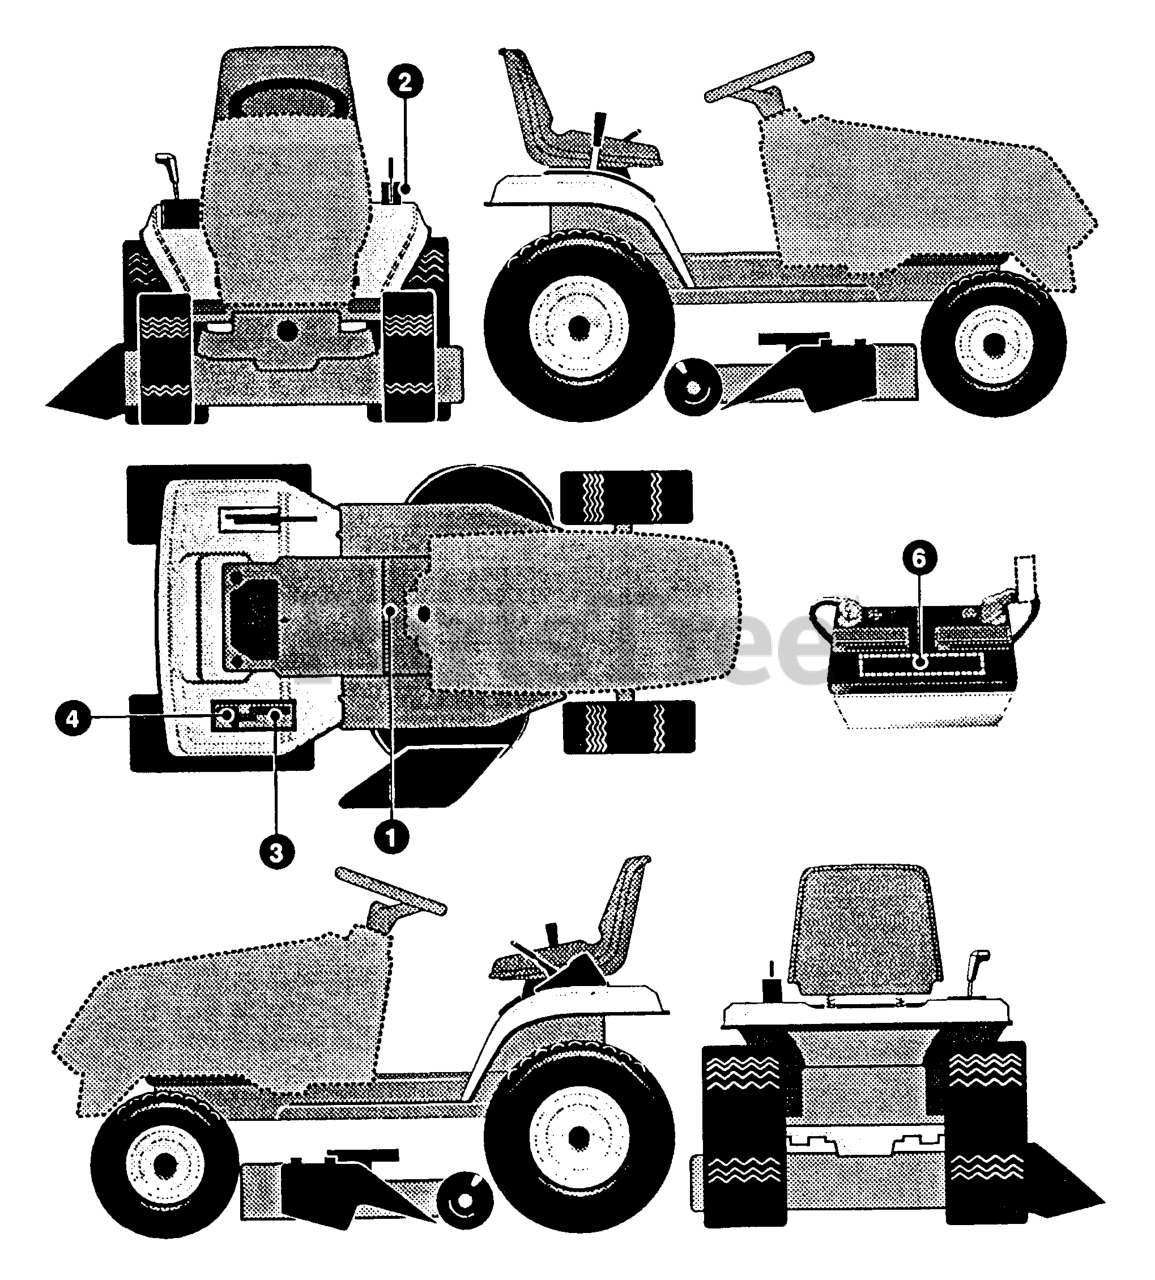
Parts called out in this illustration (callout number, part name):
1	CAUTION CONSOLE
2	HEIGHT ADJUST
3	SHIFTER POSITION
4	REV-NEUTRAL
6	BATTERY-FRE/ENG
